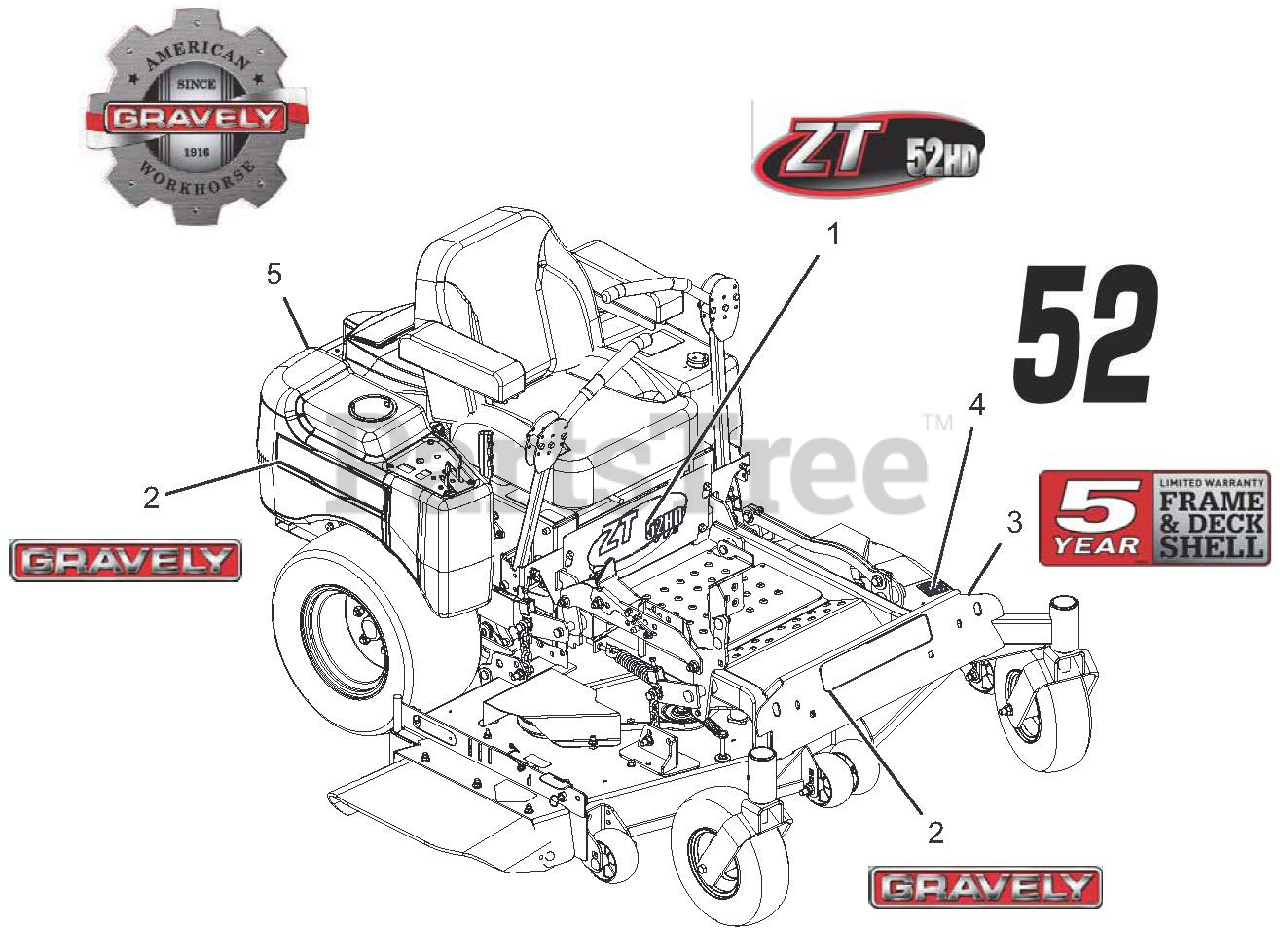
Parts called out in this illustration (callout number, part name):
1	DECAL, 52HD
2	DECAL, FUEL TANK - GRAVELY
3	DECAL, DECK WARRANTY - FAB GRAVELY
4	DECAL, 52"
5	DECAL, GRAVELY HERITAGE - SMALL
